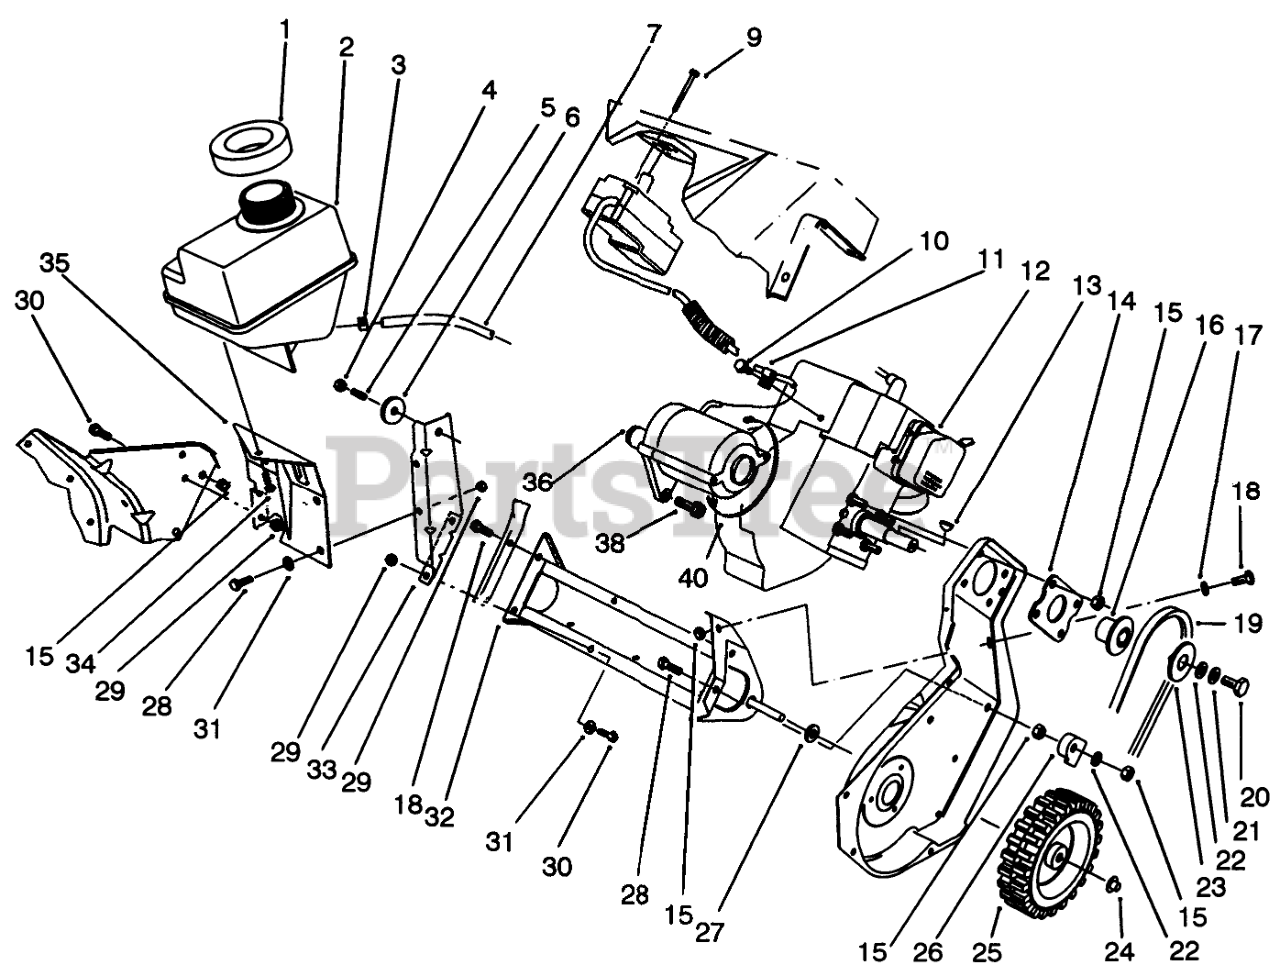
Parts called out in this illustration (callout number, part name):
1	SEAL-FOAM
2	Tank-Gas
3	Clamp
4	NUT-LOCK, NI
6	WASHER-SUPPORT, ENGINE
7	LINE-FUEL
9	SCREW-PLASTITE
10	SCREW-HWH
11	CLAMP
12	Engine Assy.
13	KEY-WOODRUFF
14	Plate Engine
15	NUT-LOCK, NI
16	Hub-HALF SHEAVE
17	WASHER-PLAIN
18	SCREW-HH
19	V-BELT
20	SCREW-HH
21	WASHER-BELLEVILLE
22	WASHER-FLAT
23	CAP-HALF SHEAVE
24	RETAINER-PUSH ON
25	WHEEL
26	GUIDE-CABLE
27	SPACER-PLASTIC
28	SCREW-HH
29	NUT-LOCK, NI
30	SCREW-HH
31	WASHER-FLAT
32	Frame Assembly
33	Support-Engine
34	SCREW-SHWH, THREAD FORMING
35	Bracket-Fuel Tank
36	Starter Switch Assembly
38	SCREW-HH, TORX
40	TIE-CABLE
